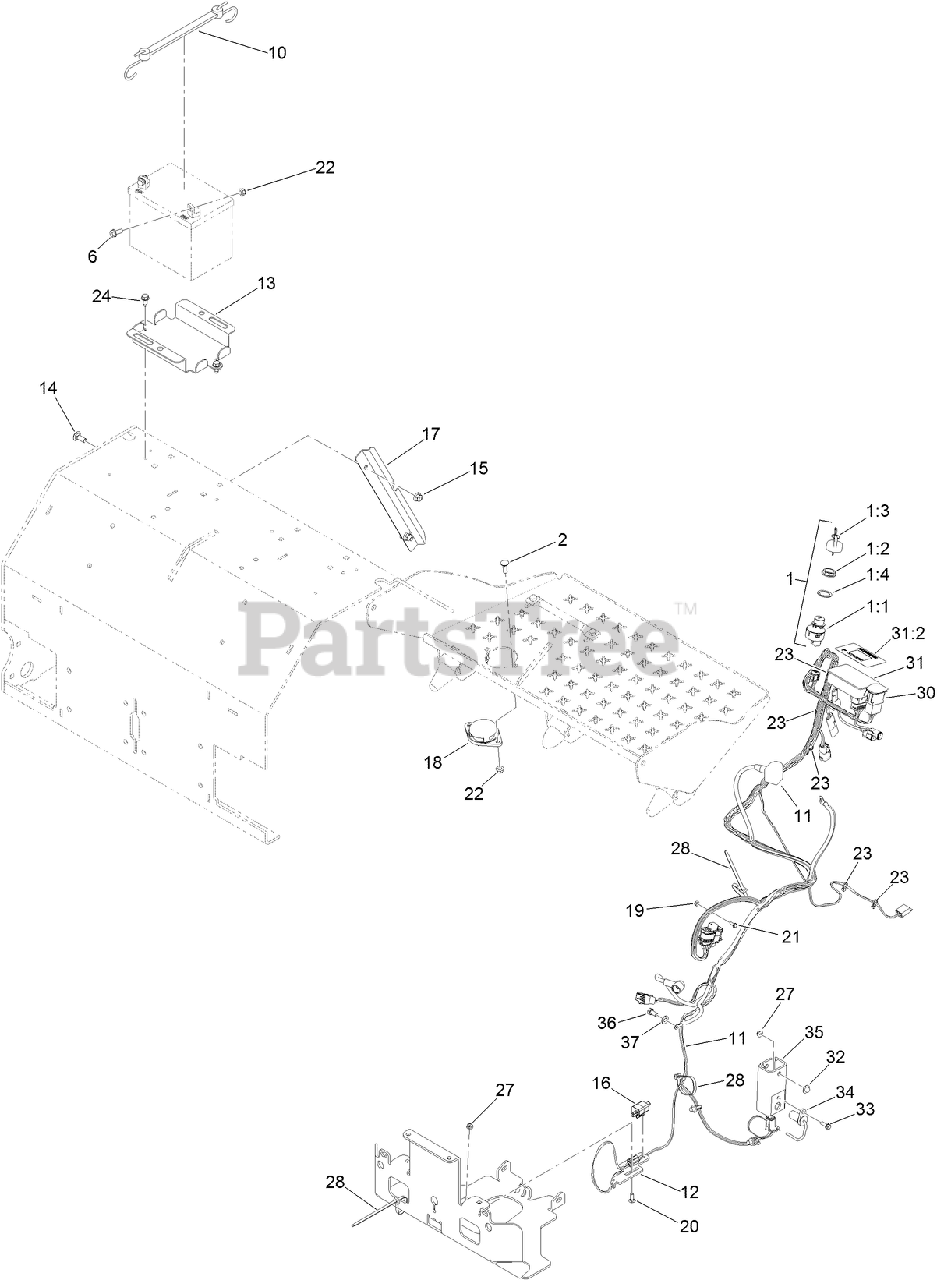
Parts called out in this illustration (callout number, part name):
1	IGNITION SWITCH ASM
1:1	HUB and BEARING ASM
1:2	NUT-MOUNTING
1:3	IGNITION KEY SET
1:4	WASHER-BACKUP
2	BOLT-CARR
6	SCREW-HHF
10	HOLDDOWN-BATTERY
11	HARNESS-WIRE
12	MOUNT-SWITCH
13	BRACKET-BATTERY
14	BOLT-CARR
15	NUT-HF, NI
16	SWITCH
17	GUARD-HARNESS
18	SWITCH-SEAT
19	NUT-LOCK, NI
20	BOLT-CARR
21	SCREW-HWH
22	NUT-HF, NI
23	TIE-CABLE
24	SCREW-HWHTF
27	NUT-HF
28	TIE-PLASTIC
30	SWITCH
31	HOUR METER ASM
31:2	DECAL-METER, HOUR
32	NUT-PUSH
33	SCREW-HWH
34	SENSOR, QUADRATURE
35	HOUSING-DEPTH CONTROL 30
36	SCREW-HH
37	WASHER-PLAIN
